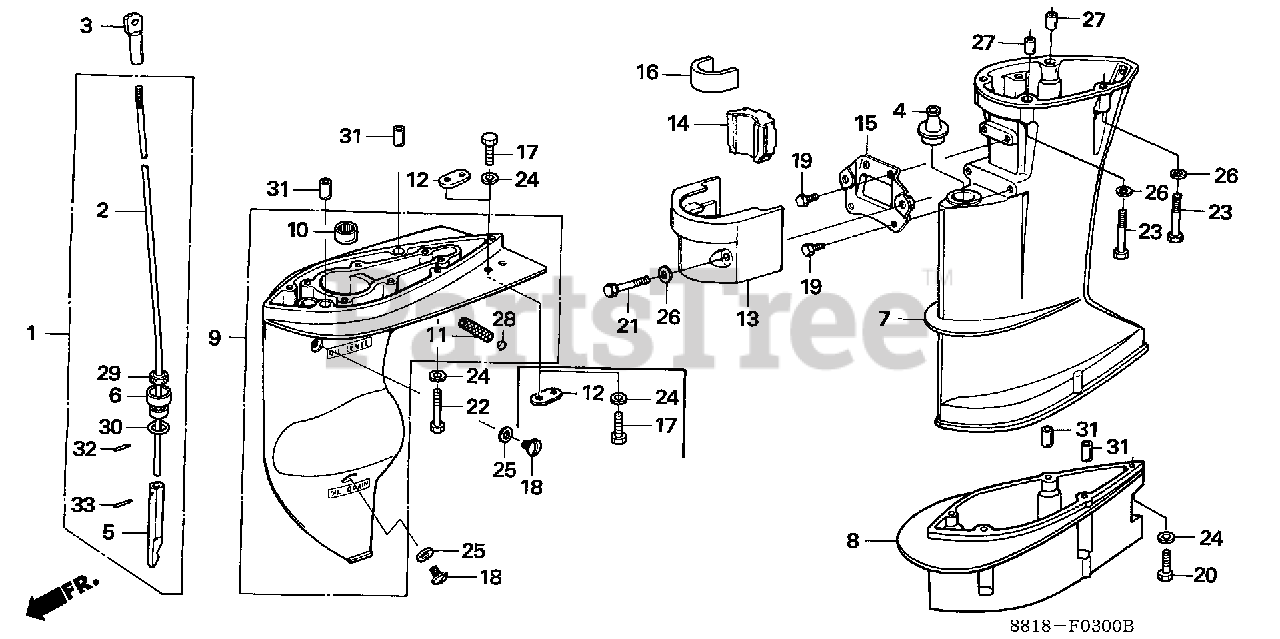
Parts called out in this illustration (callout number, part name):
1	ROD, GEARSHIFT (S)
2	ROD, GEARSHIFT (S)
3	JOINT, GEARSHIFT ROD
4	GROMMET, ROD (ARAI)
6	HOLDER, SEAL
7	CASE, EXTENSION *NH282MU* (S) (OYSTER SILVER METALLIC-U)
9	CASE, GEAR *NH282MU* (OYSTER SILVER METALLIC-U)
10	BEARING, NEEDLE (15X21X16)
11	SCREEN, WATER
12	METAL, ANODE
13	HOUSING, MOUNTING (LOWER) *NH282MU* (OYSTER SILVER METALLIC-U)
14	RUBBER A, MOUNTING (LOWER)
15	PLATE, MOUNTING (LOWER)
16	RUBBER B, MOUNTING (LOWER)
17	BOLT, HEX. (6X18)
18	BOLT, OIL CHECK (8X8)
19	BOLT, HEX. (6X12)
21	BOLT, HEX. (8X40)
22	BOLT, HEX. (6X40)
23	BOLT, HEX. (8X50)
24	WASHER, PLAIN (6MM)
25	WASHER, NYLON (8MM)
26	WASHER, PLAIN (8MM)
27	PIN A, DOWEL (10X14)
28	PLUG, SEALING (10MM)
29	SEAL, WATER (6MM)
30	O-RING (13.8X2.5)
31	PIN, DOWEL (8X10)
32	PIN, SPRING (2.5X12)
33	ROLLER (2.5X11.8)
